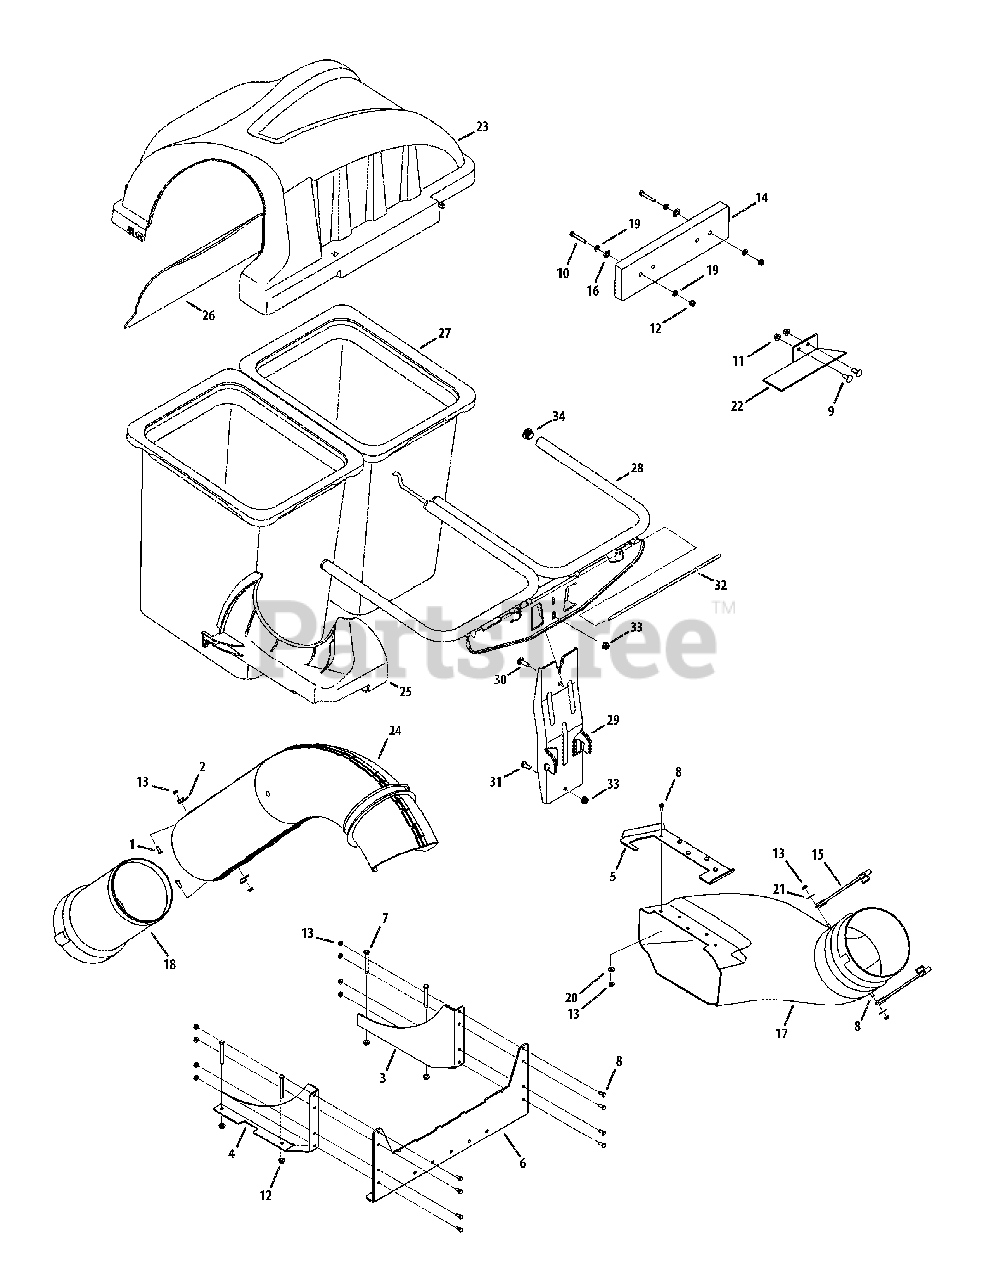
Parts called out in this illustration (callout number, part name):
1	Cap Screw, 1/4-20 x .750
2	Retainer Hook Bracket
3	Mount Assembly, RH
4	Mount Assembly, LH
5	Boot Mount Bracket
6	Catcher Mounting Bracket
7	Hex Head Screw, 5/16-18 x 2.75
8	Hex Head Screw, 1/4-20 x .620
9	Carriage Bolt, 3/8-16 x 1.00
10	Hex Head Screw, 5/16-18 x 2.00
11	Flange Lock Nut, 3/8-16
12	Flange Lock Nut, 5/16-18
13	Flange Lock Nut, 1/4-20
15	Chute Strap
16	Push Nut, 5/16
17	Discharge Chute Elbow
18	Chute Adapter
19	Flat Washer, .375 x .738 x .063
20	Belleville Washer
21	Flat Washer, .265 X 1.0 X .030
23	Twin Bagger Cover Assembly
24	Upper Chute Assembly
25	Upper Chute Support
26	Bagger Cover Screen
27	Grass-bag Assembly
28	Twin Bag Support Assembly
29	Vertical Support Bracket
30	Carriage Screw, 5/16-18 x 1.00"
31	Hex Head Screw, 5/16-18 x .75"
32	Cover Hinge Pin
33	Flange Lock Nut, 5/16-18
